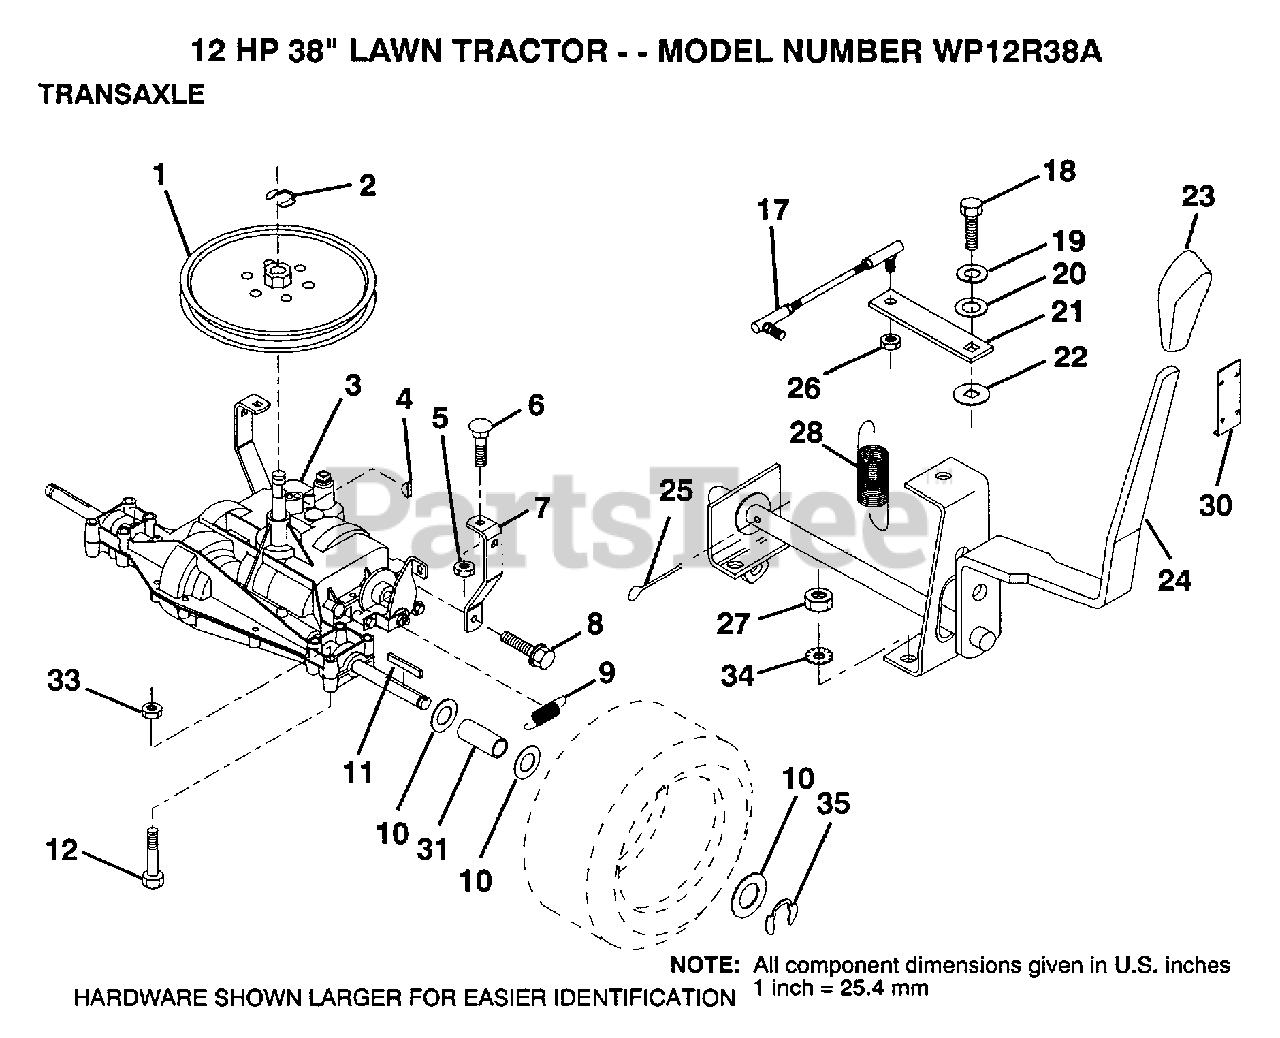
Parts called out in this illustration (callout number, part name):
1	PULLEY
6	BOLT
7	"STRAP,TORQUE"
8	SCREW
10	WASHER
11	SQUARE KEY
12	BOLT
17	"LINK,SHIFT"
19	LOCKWASHER
20	WASHER LT
21	"ARM,SHIFT"
22	WASH-SHFT PLT LT
23	"KNOB,SHT CONTROL"
25	PIN COTTER 1/8
26	NUT.LOCK.5/16-24
28	"SPRING,EXT"
30	KNOB RETAINER
31	SPACER
34	LOCKWASHER.5/16.E
35	E-RING LT
